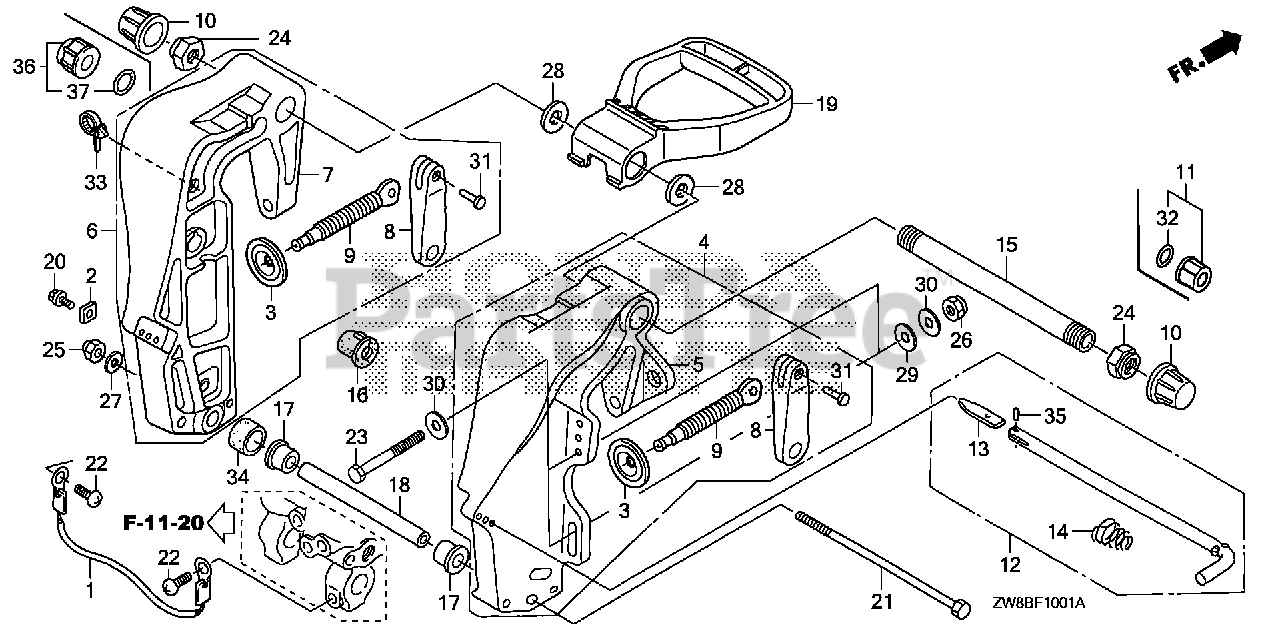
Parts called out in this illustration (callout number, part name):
1	WIRE, LEAD (1.5X170MM)
2	METAL, ANODE
3	PLATE, PUSH
4	BRACKET, R. STERN *NH282MU* (OYSTER SILVER METALLIC-U)
5	BRACKET, R. STERN *NH282MU* (OYSTER SILVER METALLIC-U)
6	BRACKET, L. STERN *NH282MU* (OYSTER SILVER METALLIC-U)
7	BRACKET, L. STERN *NH282MU* (OYSTER SILVER METALLIC-U)
8	GRIP, CLAMP
9	SCREW, CLAMP
10	CAP, TILTING BOLT
12	ROD, ADJUSTING
13	STOPPER, ROD
14	SPRING, ADJUSTING ROD
15	SHAFT, TILTING
16	BUSH, MOTOR CODE
17	BUSH, CYLINDER (LOWER)
18	COLLAR, CYLINDER (LOWER)
19	HANDLE, CARRYING REMOTE
20	BOLT, FLANGE (6X12)
21	BOLT, HEX. (8X203)
22	SCREW, PAN (6X8)
24	NUT, SELF-LOCK (7/8-14UNF)
25	NUT, SELF-LOCK (8MM)
27	WASHER, PLAIN (8MM)
28	WASHER, WAVE (22MM)
31	RIVET (4X22.6)
33	CLIP, HARNESS BAND (145MM) (BLACK)
34	COLLAR, DISTANCE
35	PIN, SPRING (2.5X8)
